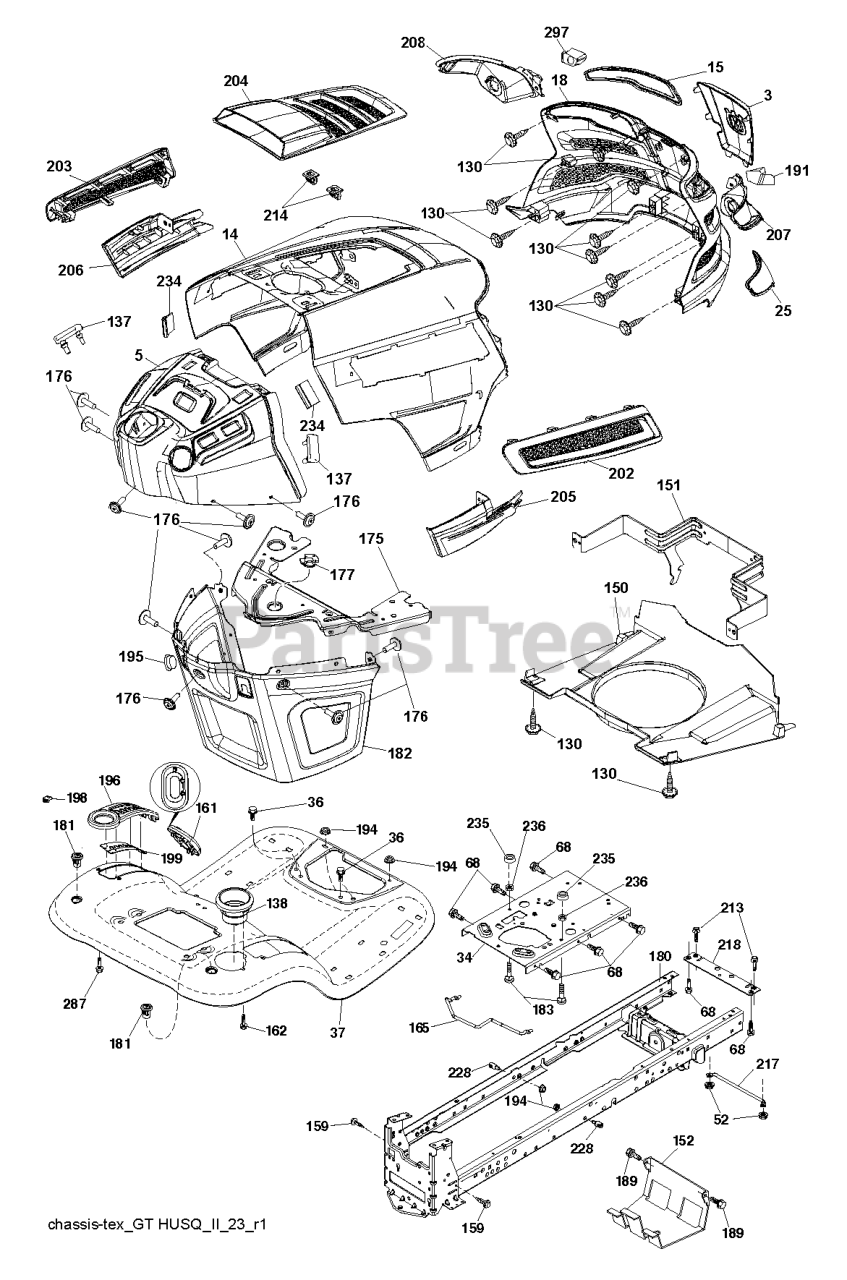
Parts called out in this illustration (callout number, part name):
3	APPLIQUE.SUBASM.GT.HUSQ.II
5	RP.DASH.UPP.GT2.SM.MC.CHOKE
14	HOOD.ASM.HUSQVARNA.GT.TEX.422
15	LENS.HEADLIGHT.LH.GTII.2011
18	GRILLE.SUBASM.GT.HUSQ.II
25	LENS.HEADLIGHT.RH.GTII.2011
34	PLATE.ENGINE.WELDED.CHASSIS
36	SCREW 5/16"
37	FENDER.TLT.W/CPH.W/FW.ORANGE
52	LOCKNUT
68	Screw 5/16-18 x 1/2 Hex, Self Tapping 5/16-18 x 1/2
130	SCREW.#10 X 0.750.BOS
137	BUMPER DASH
138	CUPHOLDER.TL.TEX.418
150	AIR DUCT.GTV2(1.66"RING HEIGHT
151	BRACKET.PIVOT.HOOD.GT.HUSQ.II
152	SHIELD.BROWNING.W/TEX
159	SCREW, 3/8-16X3/4
161	WINDOW.FUEL.LT.HUSQ.TEX.418
162	SCREW.HI-LO.CONSOLE
165	SUPPORT.TANK.REAR.W/TEX
175	PLATE.CROSSMEMBER.HUSQ
176	SCREW.#10-24X5/8.RN.QU
177	BUSHING, STEERING
180	CHASSIS
181	BUSHING.MNT.FEND.CRGO.
182	DASH.LOWER.COMMON.12V.ADAPTOR
183	BOLT.5/16-18X1-1/4 FULL THD
189	SCREW
191	INSERT.REFLECTIVE.RH.HUSQ.GTII
194	NUT LOCK HEX FLANGE 5/16-18
195	PLUG.HOLE.DASH.LOWER.12V.BLK
196	RP CONSOLE.ASM.DECKLFT.GR/RBT.
198	INDICATOR DECK LIFT
199	PLATE.DECK.LIFT.HUSQ.LT
202	VENT.SIDE.RH.GT.HUSQ.II.
203	VENT.SIDE.LH.GT.HUSQ.II.498
204	VENT.TOP.HUSQ.GT2
205	SIDE.TRIM.RH.GT.HUSQ.II
206	SIDE.TRIM.LH.GT.HUSQ.II.GRAY
207	BEZEL LIGHT.RH.GT.II.MYLAR
208	BEZEL LIGHT.LH.GT.II.MYLAR
213	BOLT
214	CLIP.RETAINER.TINNER.
217	ROD.PIVOT.HOOD
218	X-PIECE.HOOD.STOP.NON/
228	STUD.FASTNER.W/ANTI-ROTATE
234	BUMPER.HOOD.TEX.HUSQVARNA
235	SPACER FENDER
236	NUT.CENTERLOCK.5/16-
287	SCREW 1/4X20
297	INSERT.REFLECTIVE.LH.HUSQ.GTII
